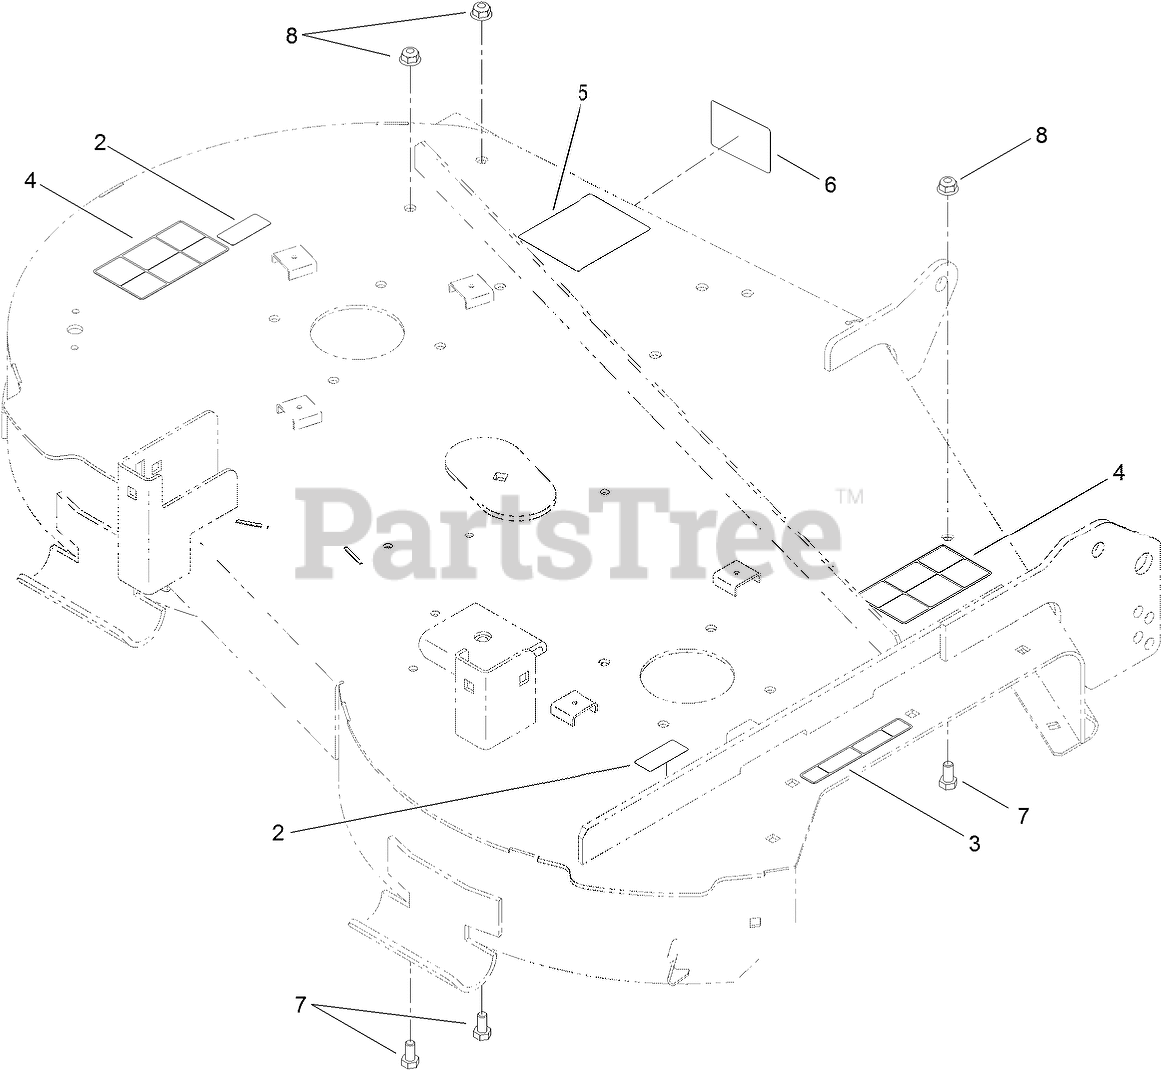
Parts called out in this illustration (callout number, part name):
2	DECAL-DANGER
3	DECAL-DANGER
4	DECAL-DANGER
5	DECAL-ROUTING, BELT
6	DECAL-SCALP, ANTI
7	SCREW-HH
8	NUT-HF, NI
